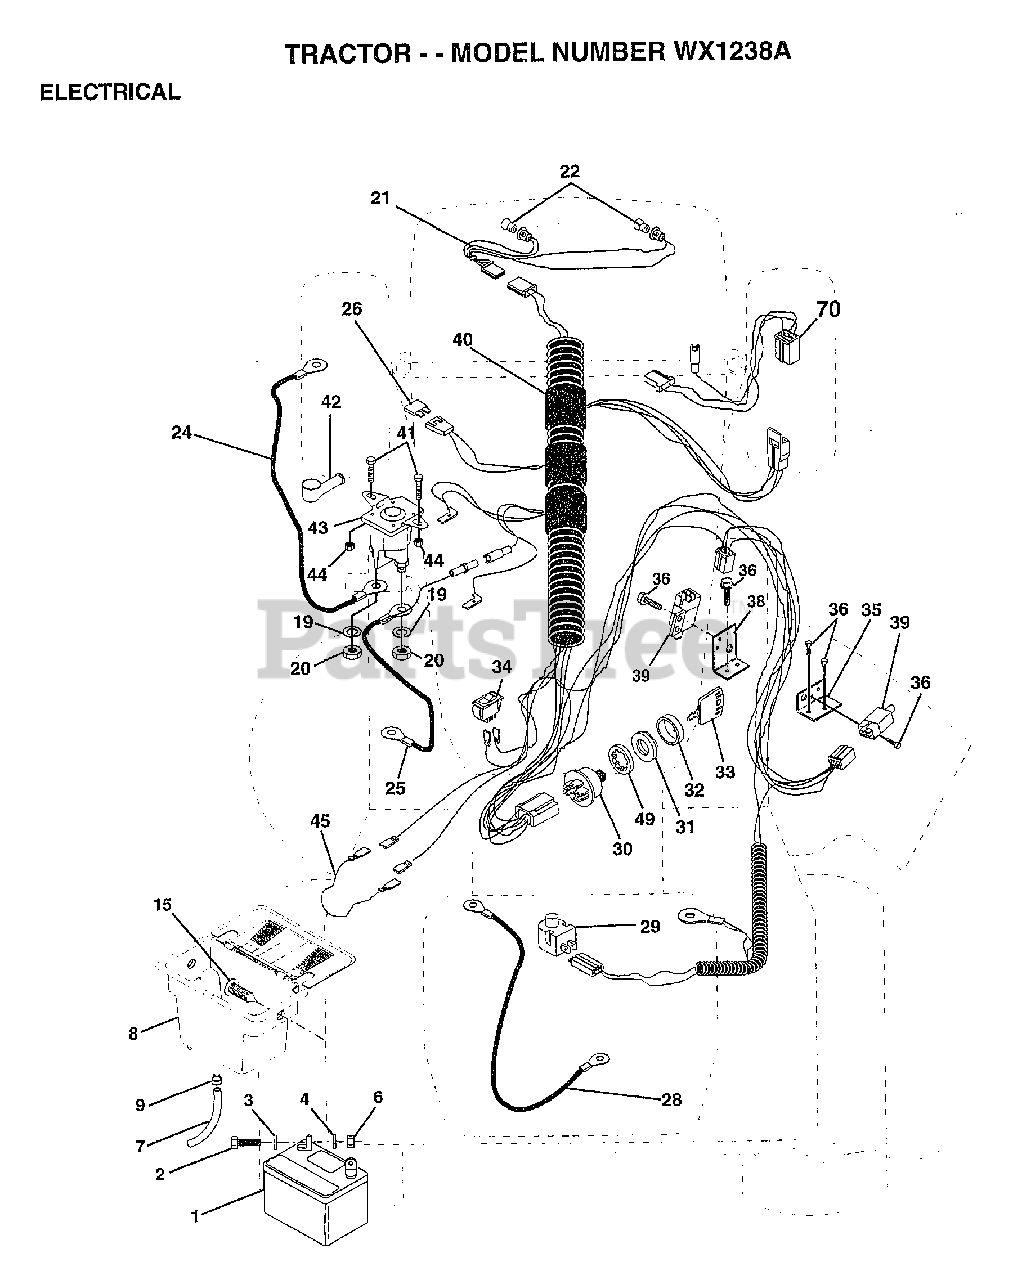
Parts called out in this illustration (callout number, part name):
2	BOLT LT
3	WASHER
4	LOCKWASHER
7	TUBE T
9	HOSE CLAMP T
15	FASTNER.SNAP-IN
20	NUT
21	"HARNESS,LIGHT SOC"
22	HEADLAMP BULB
24	"CABLE T, BATTERY"
25	CABLE.BTRY.6GA.RD
26	FUSE HYT
28	CABLE T
29	SWITCH SEAT
32	COVER KEY SWITCH
33	KEY MLD GEN DELTA
34	SWITCH LT
35	BRACKET LT
36	SCREW
38	BRACKET SWITCH IN
39	SWITCH INTERLOCKT
40	HARNESS.IGN.DASH.
41	BOLT HXHD FIN
44	NUT HXKEP 1/4X20
45	ADAPTER AMMETER
49	LOCKWASHER
70	HARNESS ENG DUAL
